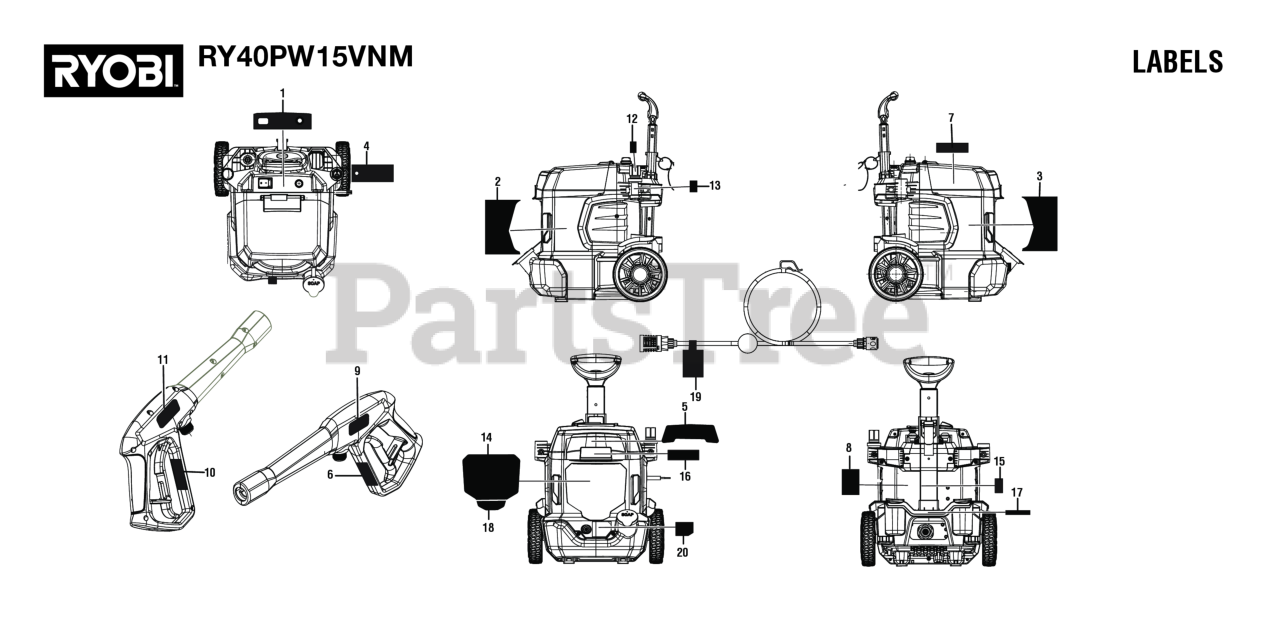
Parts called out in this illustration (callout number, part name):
1	On/Off Label
2	Warning Label (Eng)
3	Warning Label (Fr)
4	Starting Instructions Label
4	Spanish Hangtag
4	Nozzle Hangtag (PS141913)
5	Battery Notice Label
6	Trigger Handle Data Label
7	Inquires Label (Ryobi)
8	Data Label
9	Trigger Handle Warning Label (English)
10	Trigger Handle Warning Label (French/Spanish)
11	Trigger Handle Label (Logo Label)
12	Adaptor Label
13	Adaptor Location Label
14	Performance Label
15	QR Code Label
16	Ryobi Logo Label
17	Self-Priming ACC Instruction Label
18	Self-Priming Notice Label
19	Siphon Hose Wrap Label
20	Soap Dilution Label
